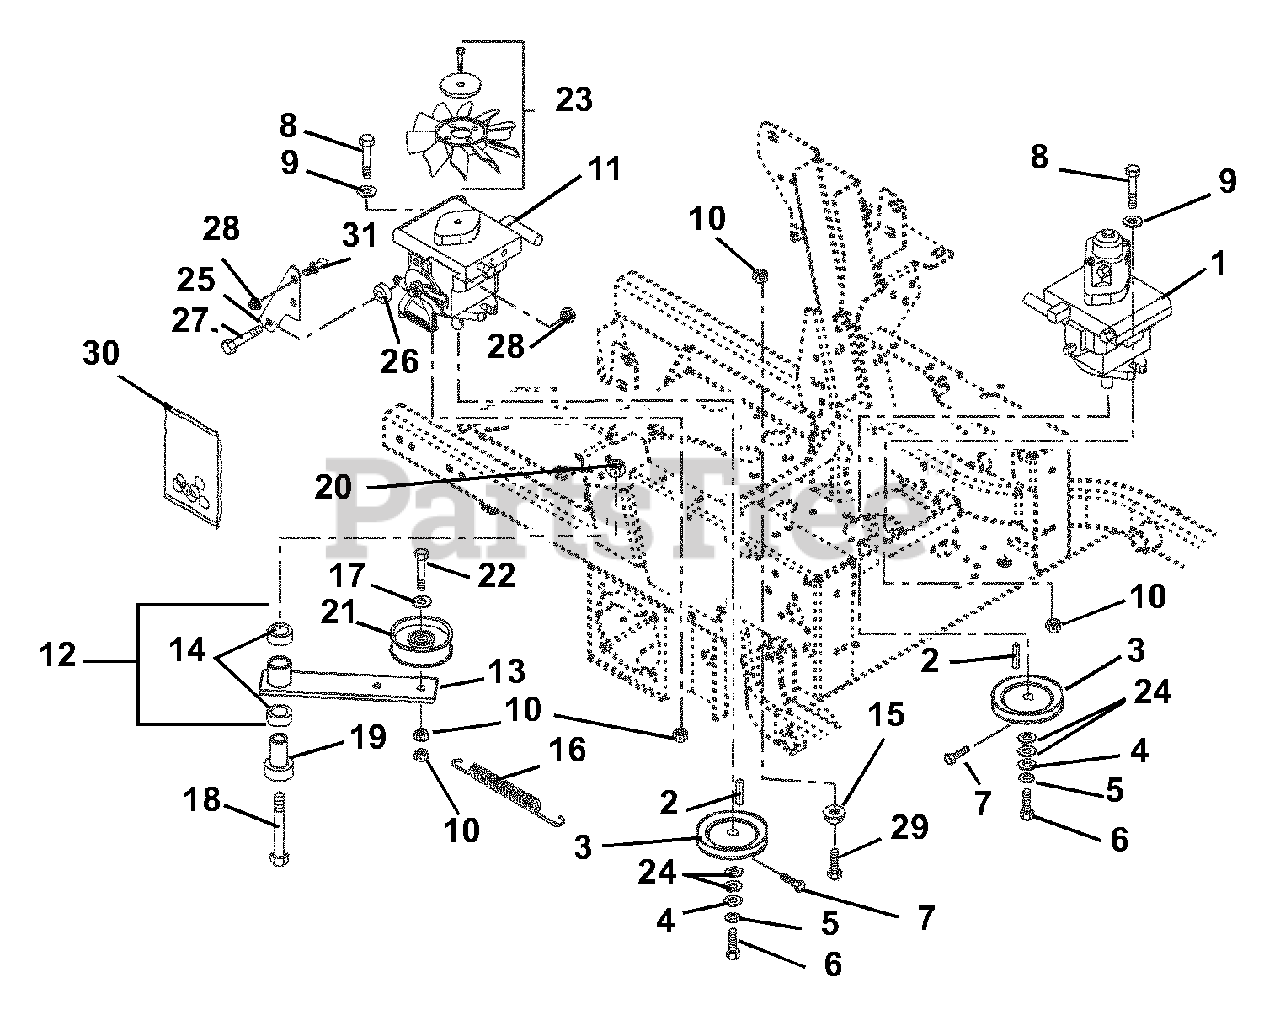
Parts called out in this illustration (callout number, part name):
1	Hydrostat BDP with Auxiliary (077, 078, 179, 080, 081, 082, 310, 311)
1	Pump, Hydraulic BDP-10A Left Hand (064, 083)
2	Key, Straight 5mm x 25mm x 5mm
3	Sheave 4.0 x .199
4	Washer, Flat Steel .281 x 1.00 x .063
5	Washer, Locking .25 x .062
6	Bolt, Hex M6 x 1.0 x 12
7	Bolt, Hex .25-20 x .50 Grade 5
8	Bolt, Hex .38-16 x 1.25 Grade 5
9	Washer, Flat Steel .39 x .75 x .125
10	Nut, Locking Top Flange .38-16
12	Assembly, Idler Arm Guard Drive
13	Weldment, Idler Arm Ground Drive
14	Bearing, 1.00 x 1.12 x .75
15	Nut-Flange .375-16
16	Spring, Tension .120 x .845 x 6.50
17	Washer, Flat Steel .39 x.75 x.125
18	Bolt, Hex .50-13 x 3.50 Grade 5
19	Bearing, Pedestal Powdered Metal
20	Nut, Locking Top Flange .50-13
21	Idler, Flat 4.00 x 1.06
22	Bolt, Hex .38-16 x 2.25 Grade 5
23	Fan, Cooling
24	Washer, Flat Steel .656 x 1.31 x .095
25	Bracket, Return to Neutral/Damper
26	Spacer .344 x 1.00 x .375
27	Bolt, Hex .31-18 x 1.25 Grade 5
28	Nut, Locking Top Flange .31-18
29	Bolt-Hex .38-16 x 3.25 Grade 5
30	Kit, Pump Seal (BDP-10A)
31	Stud, Ball
